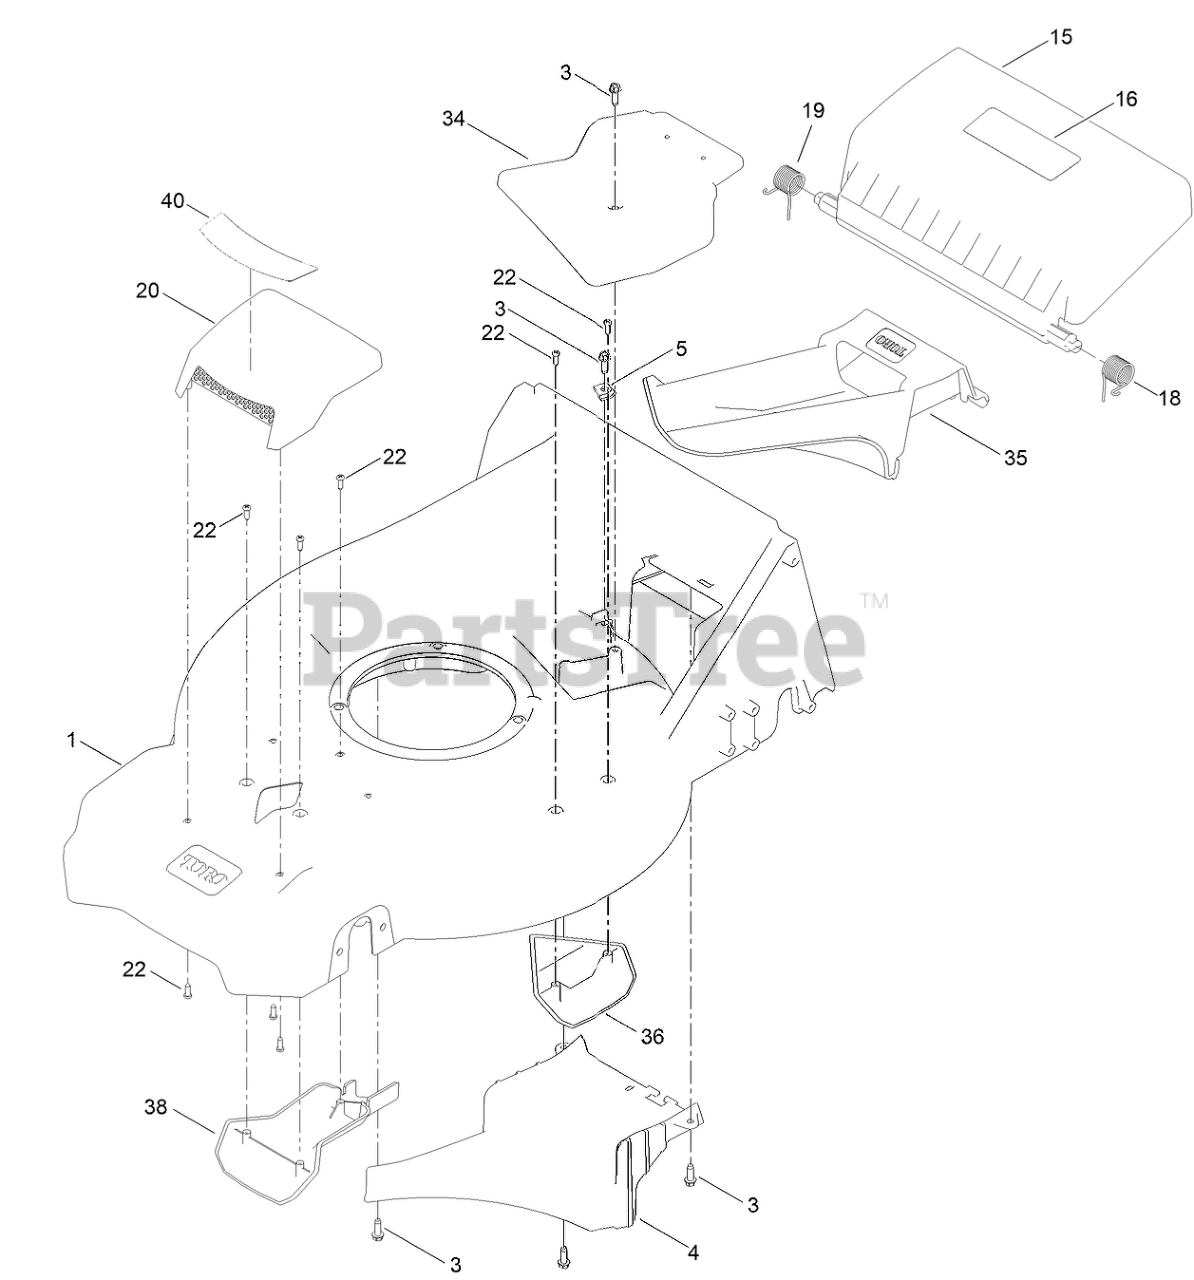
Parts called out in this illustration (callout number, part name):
1	HOUSING ASM
3	SCREW-HWHTF
4	RAMP-DISCHARGE
5	CLAMP-CABLE
15	DOOR-REAR
16	DECAL-WARNING
18	SPRING-TORSION, LH
19	SPRING-TORSION, RH
20	ASM-COVER, TOP INTAKE
22	SCREW-PLASTIC, PPH
34	COVER-BELT, TOP
35	PLUG-MULCH
36	KICKER-HOUSING
38	COVER-INTAKE, BOTTOM
40	DECAL-COVER, INTAKE
